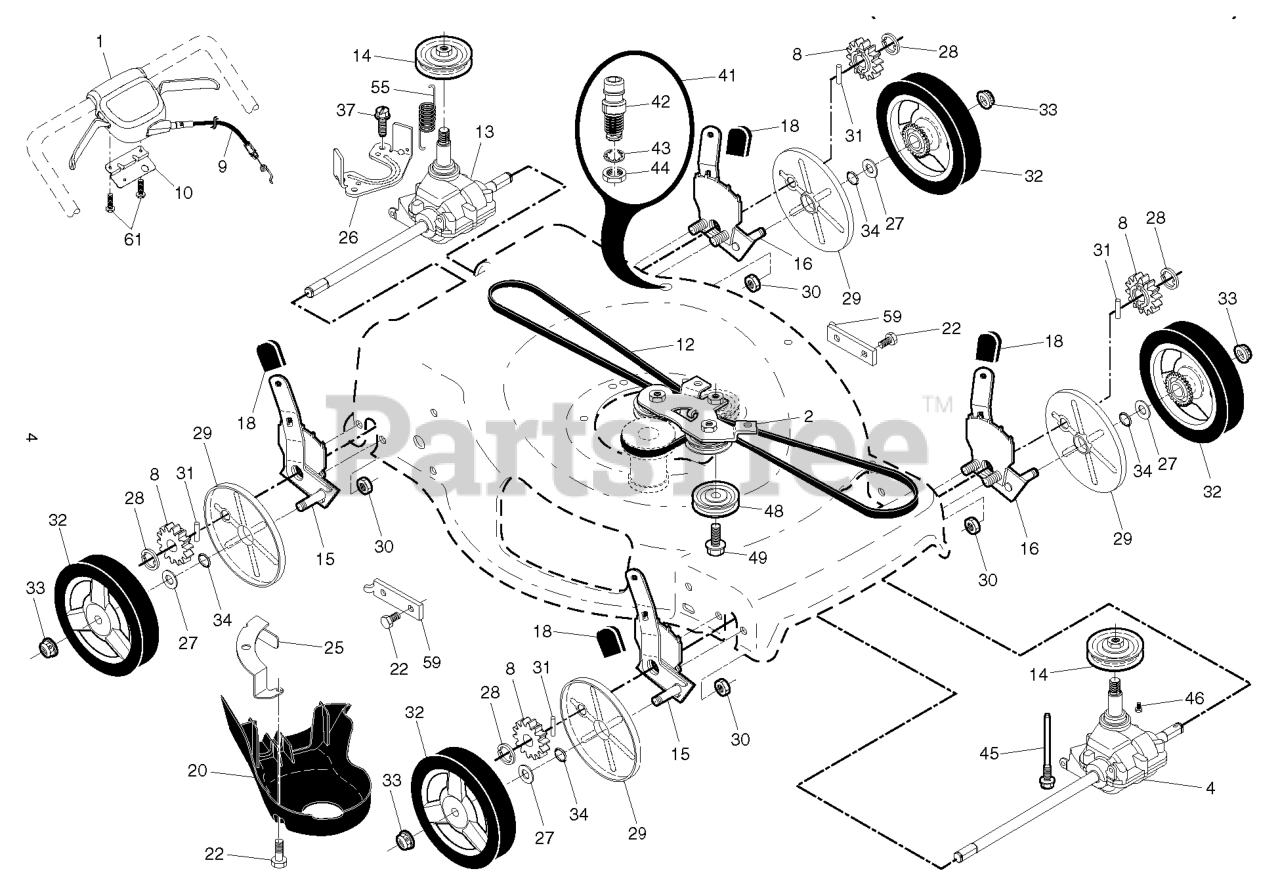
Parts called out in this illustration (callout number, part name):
1	CONTROL.AW2.22+AWD.BS.GEN SERV
2	BRACKET.ASM.AWD.BZP.BLACK
4	TRANSMISSION.22+.AWD.FRT
8	PINIION.14.TOOTH.RGD
9	CABLE.DRIVE.RWD.WALK.
10	BRACKET DUAL TRIGGER CONTROL
12	BELT.DRIVE.AWD.13 ZINC DUSTED
13	TRANSMISSION.22+AWD.WALK.MOWER
14	PULLEY.DRIVE.SM.AWD/RWD
15	HEIGHT ADJUSTER 9 POS QUICK
16	HEIGHT ADJUSTER 9 POS QUICK
18	SELECTOR KNOB
20	COVER.REAR.DRIVE.22+2013
22	BOLT.5/16HEX.WHS.HD
25	BRACKET.DRIVE.COVER.RGD.BZP
26	BRACKET.TRAN.BELTKEEPER.22+RGD
27	WASHER FLUT
28	E-RING 7/16 RE
29	COVER.DUST.WHEEL.INNER.WALK
30	NUT.FLANGE.1-4-20-SERR
31	PAWL, DRIVE
32	WHEEL.8".AWD.3SP.EXT.DR.GREY
33	NUT.HEX.FLANGE.3/8-16.LO(3 2)
34	O-RING..070X.487.NEOPRENE
41	KIT.WASH-OUT.PORT.ZINC.WALK
42	WASHOUT.PORT.ZINC.RGD.22+
43	WASHER.LOCK.INTERNAL.TOOTH
44	LOCKNUT.HEX.WITH.O-RING
45	SCREW.HI-LO.5/16-14 X 4.10
46	SCREW.HI-LO. 5/16 X 1.00
48	PULLEY.ASM.22+ AWD
55	SPRING.RETURN.AUTO.
59	BRACKET.SUPPORT.22+RWGD.BZP
61	SCREW, PHILLIPS HEAD 10 X 5/8
